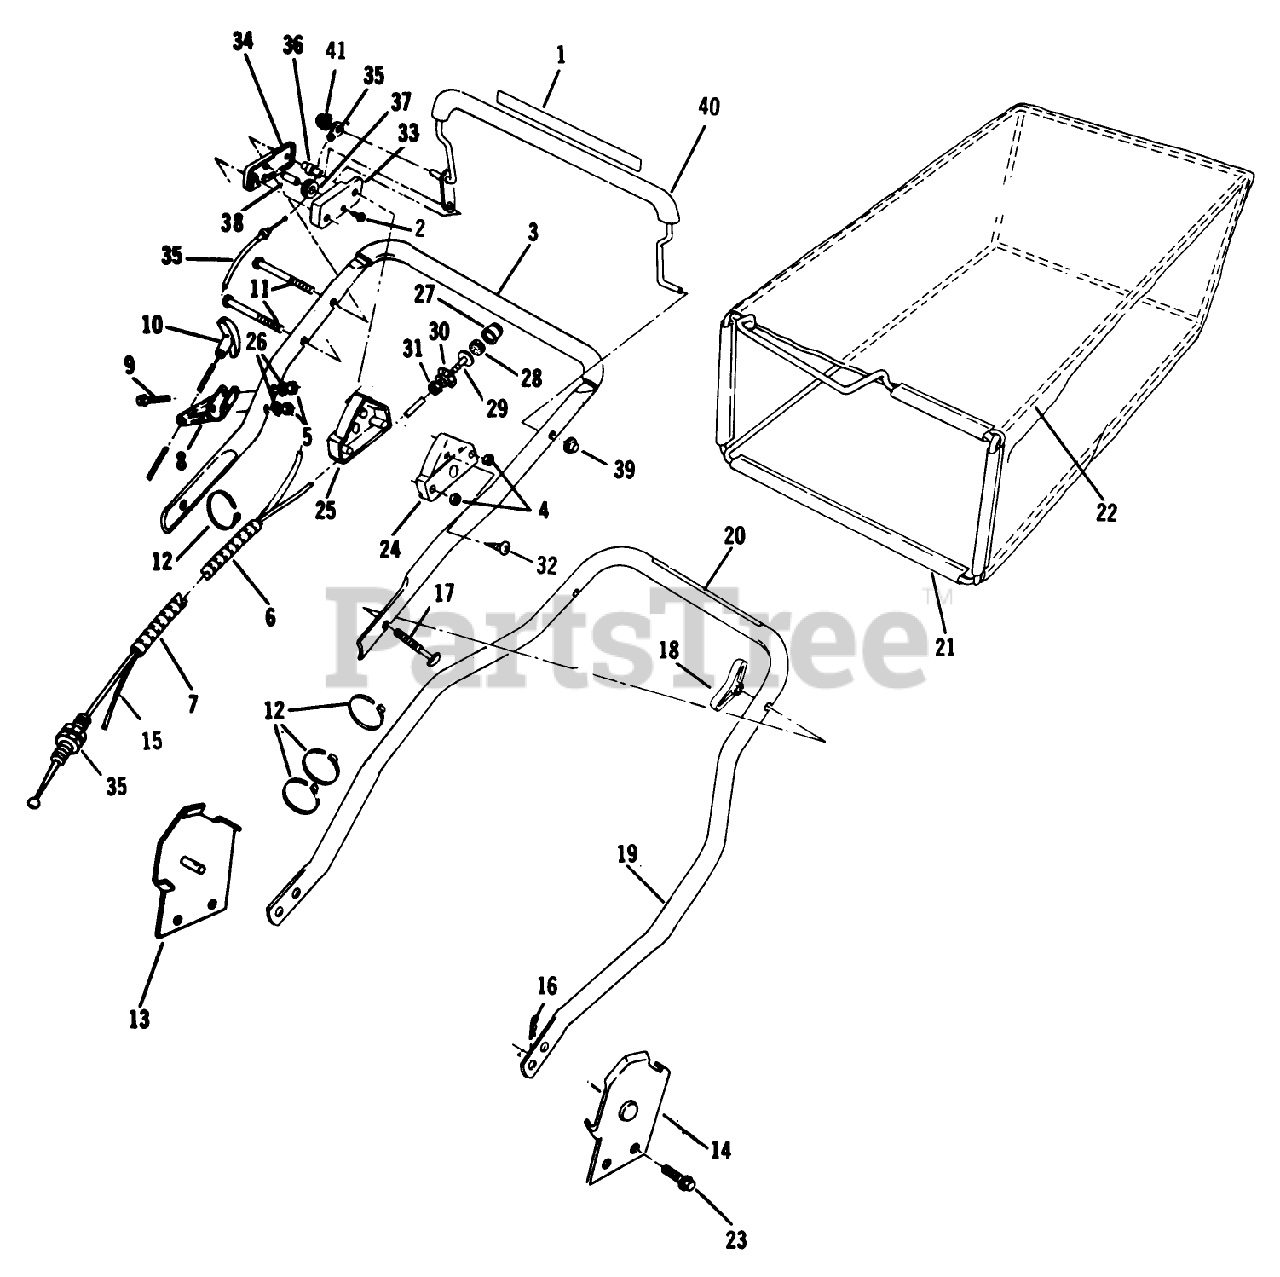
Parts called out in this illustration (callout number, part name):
2	SCREW
4	NUT C/LOCK E
5	LOCKNUT E
10	HANDLE,STARTER
16	HAIR PIN
17	BOLT QUALITY
18	NUT-WING
26	WASHER
28	FILTER S
31	LOCKNUT S
32	SCREW LAWRENCE
35	CONTROL CABLE WES
36	COLUMN
38	PIN SKF
41	NUT ACORN
